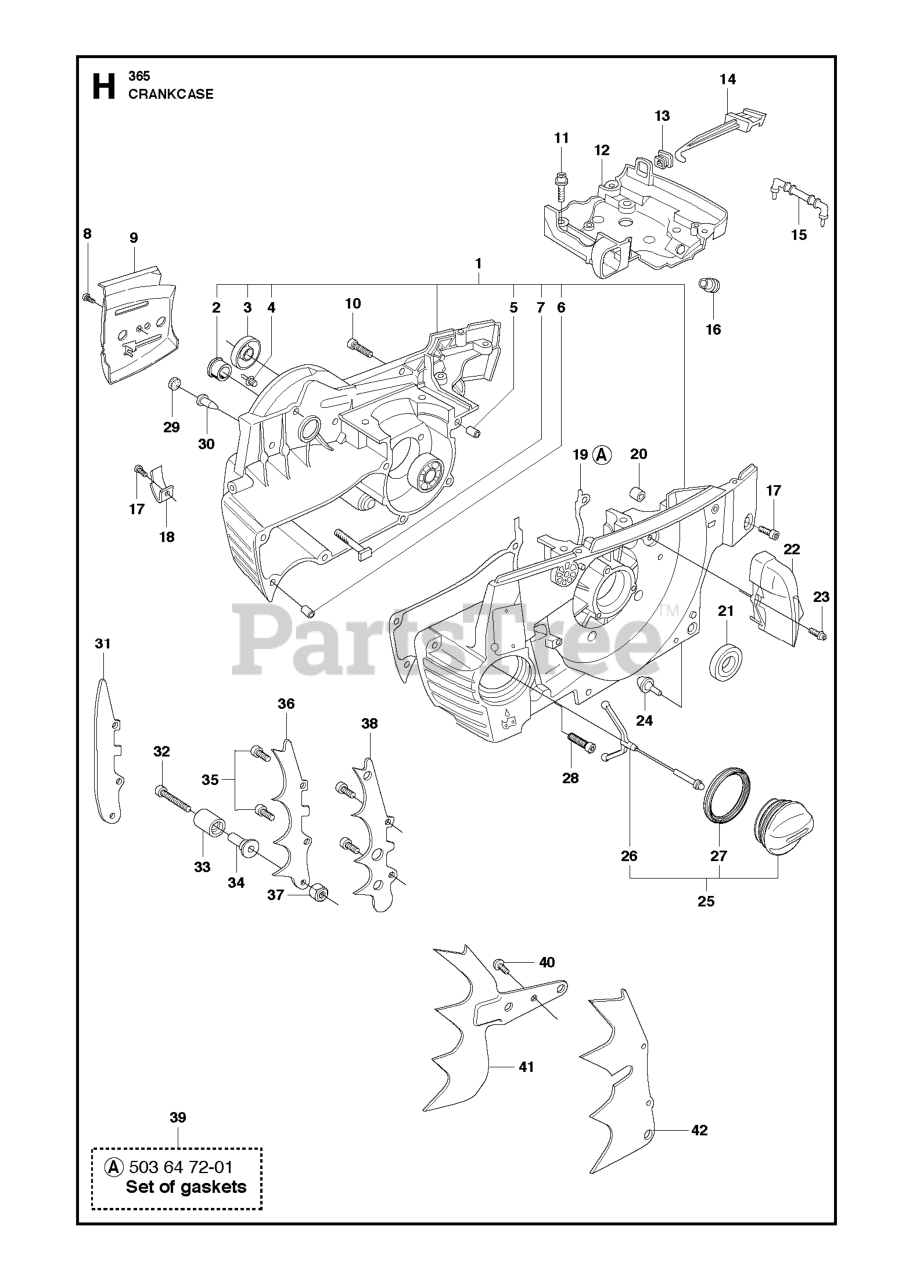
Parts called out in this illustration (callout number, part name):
1	RP CRANKCASE
11	SCREW
12	BASE
15	SPACER
17	SCREW IHSCM
18	CHAIN CATCHER
23	SCREW
25	TANK CAP
29	PLUG
30	VALVE-CHECK (DUCKBILL)
32	SCREW IHSCFM
34	CHAIN CATCHER
36	FELLING DOG
38	FELLING DOG
39	GASKET SET
41	FELLING DOG
42	FELLING DOG
